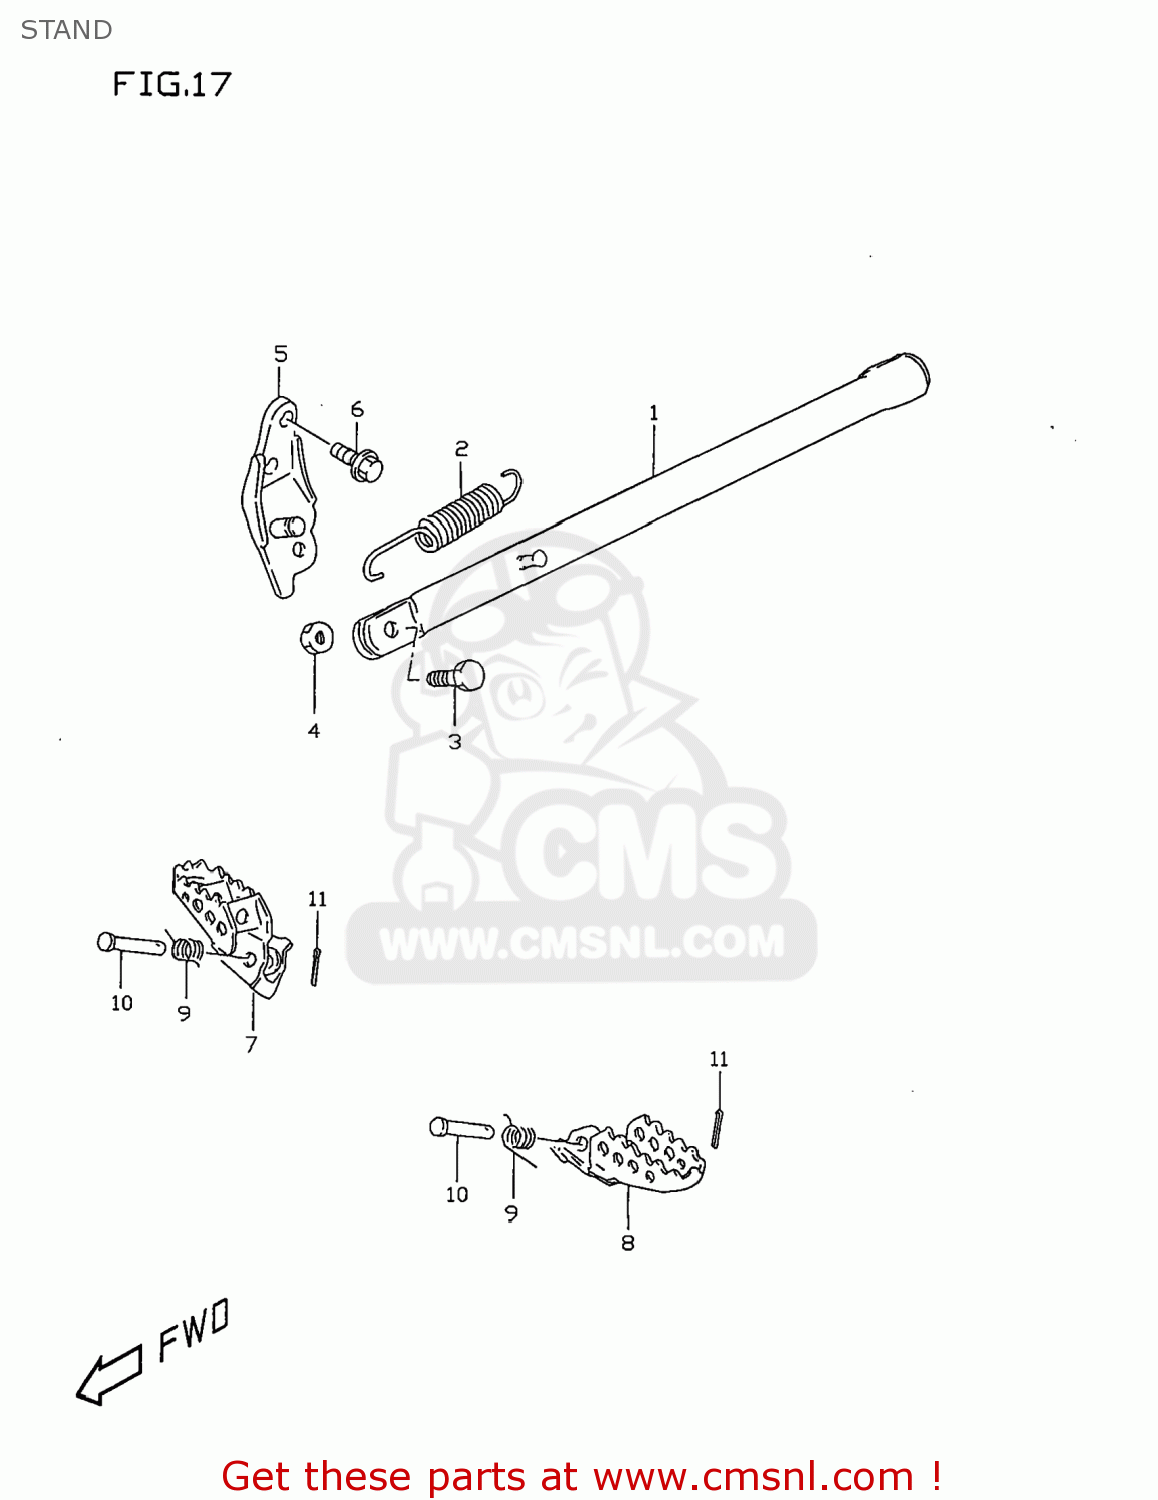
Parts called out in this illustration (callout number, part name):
1	STAND,PROP(BLACK)
2	SPRING
3	BOLT(8X25)
4	NUT
5	BRACKET,PROP STAND(BLACK)
6	BOLT
7	FOOTREST,FR,R
8	FOOTREST,FR,L
9	SPRING
10	PIN
11	PIN
